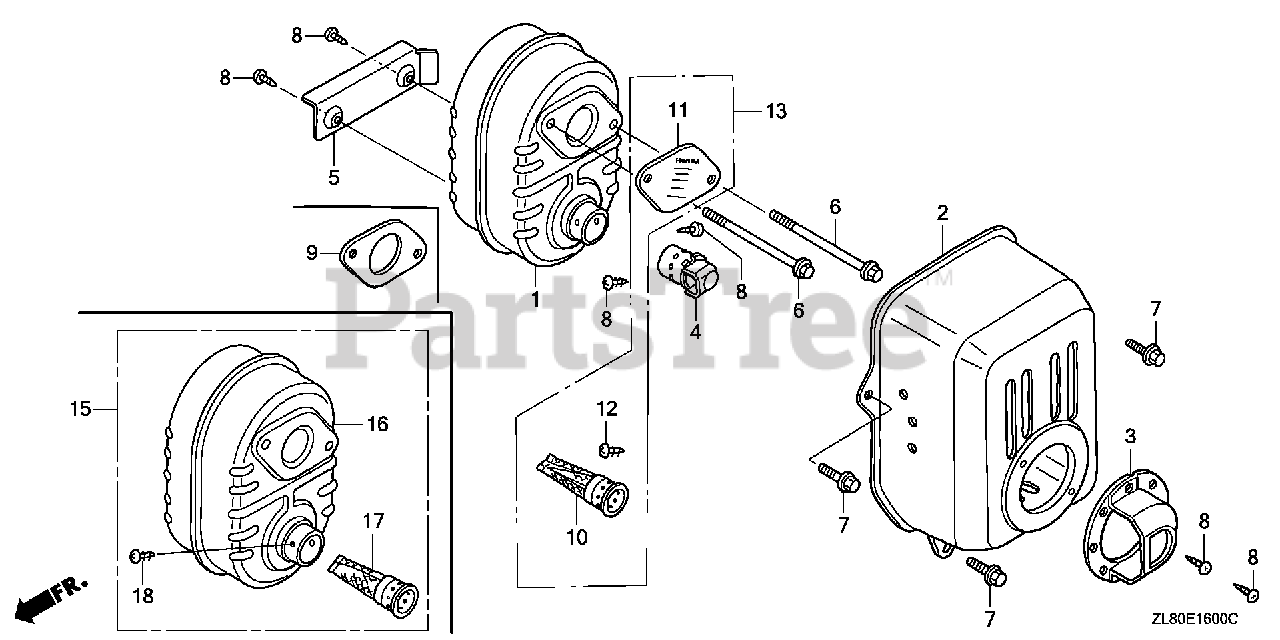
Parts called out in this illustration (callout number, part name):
2	PROTECTOR, MUFFLER
5	SHROUD, MUFFLER
6	BOLT, FLANGE (6X79) (CT200)
7	BOLT, FLANGE (6X12) (CT200)
8	SCREW, TAPPING (4X6) (TO INSTALL OPTIONAL SPARK ARRESTER)
9	GASKET, MUFFLER
10	ARRESTER, SPARK (TO 1207644)
11	PLATE, ARRESTER NUMBER (TO INSTALL OPTIONAL SPARK ARRESTER)
12	SCREW, TAPPING (4X6) (TO INSTALL OPTIONAL SPARK ARRESTER)
13	ARRESTER KIT, SPARK
